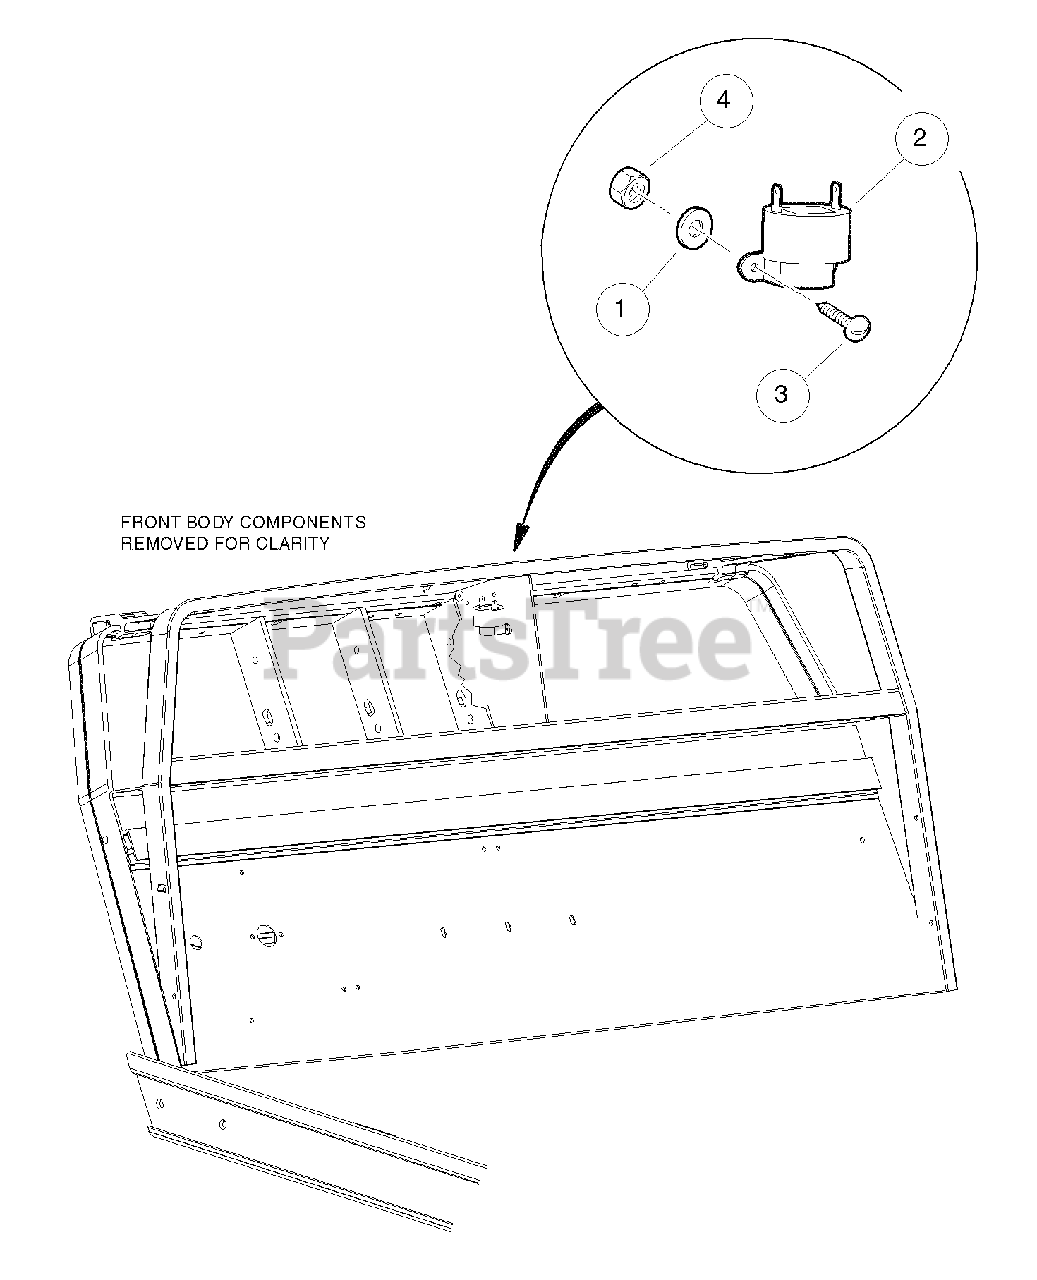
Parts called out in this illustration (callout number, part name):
1	Washer, #4 Flat
2	Buzzer, Reverse
3	Screw, #4-40 X 0.75 Round-Head Machine
4	Nut, #4-40 Hex Machine
